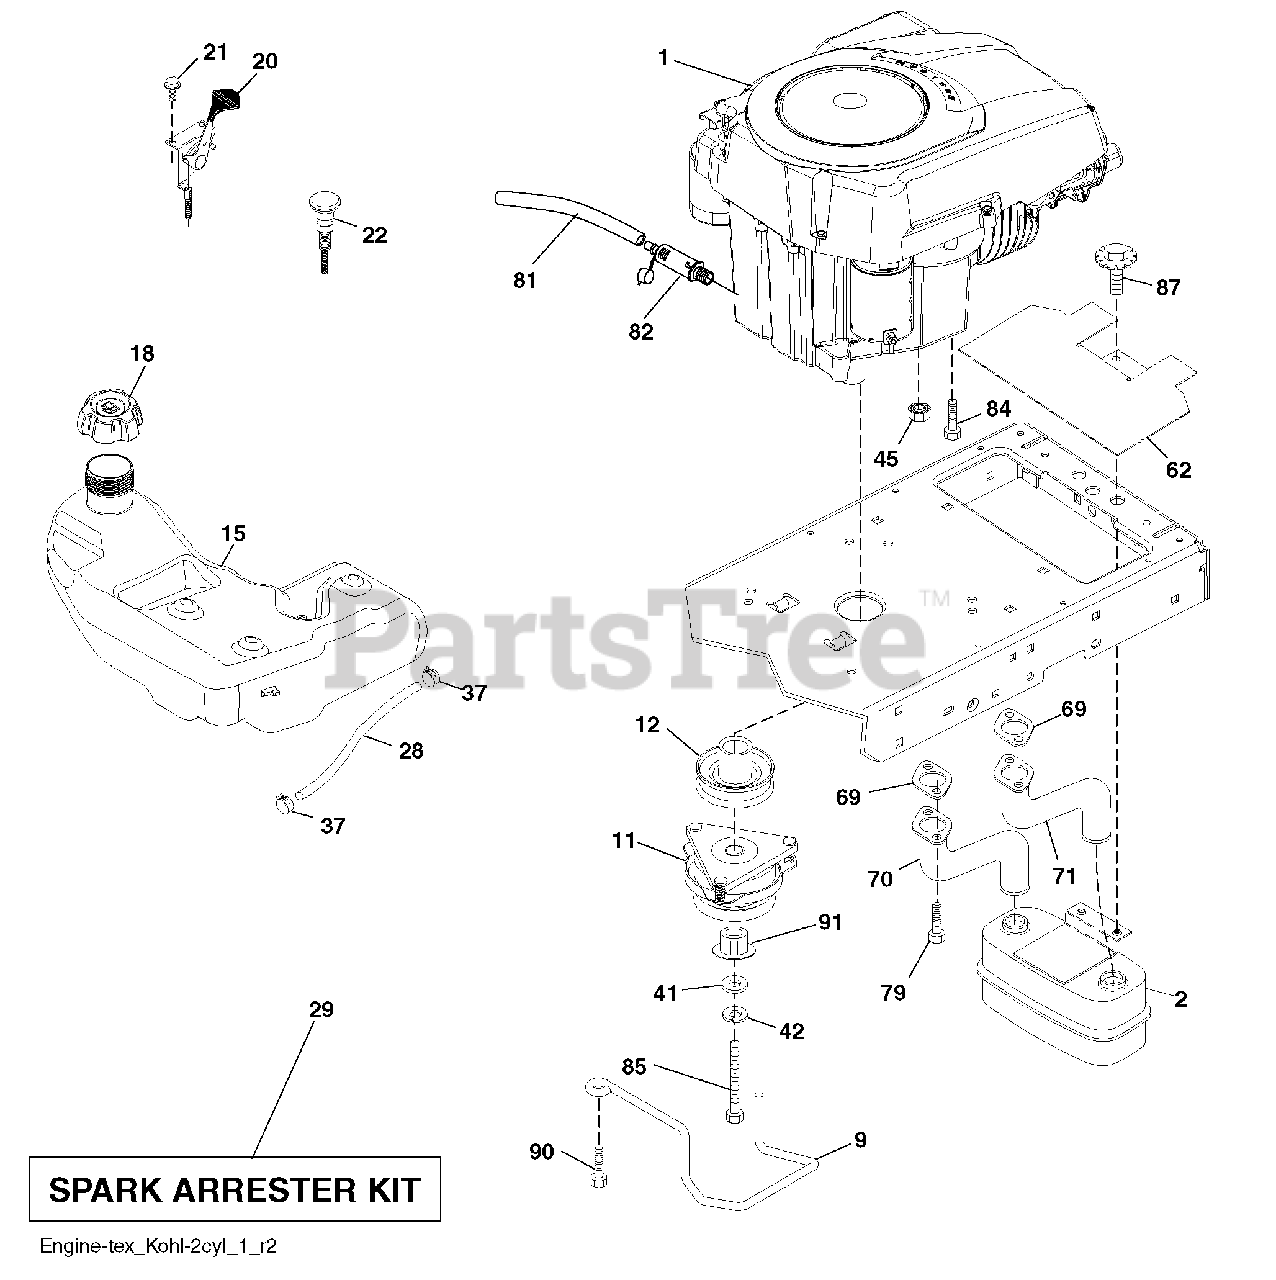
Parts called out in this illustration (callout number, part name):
9	Keeper Belt Engine
11	Clutch Electric
12	Pulley Engine
15	Tank Fuel 4.0
18	Cap Asm
20	Control Throttle
21	Screw #10 x .750 BOS Thread
22	Control Choke
28	Fuel Line
29	Spark Arrester Kit
37	Clamp Hose
41	Washer 1-1/2 OD x 15/32 ID x .250
42	Washer Lock 7/16
45	Nut Keps Hex 1/4-20 unc
62	Shield Heat Muffler
69	Gasket
70	Tube Exhaust LH
71	Tube Exhaust RH
79	Screw Socket Head 5/16-18 x .75
81	Tube Drain Oil Easy
82	Plug Drain Oil
84	Screw 3/8-16 x 1
85	Bolt Hex 7/16-20 x 3.75 Gr. 5
87	Bolt 5/16-18 unc x 1 w/Sems
90	Screw 3/8-16 x 1
